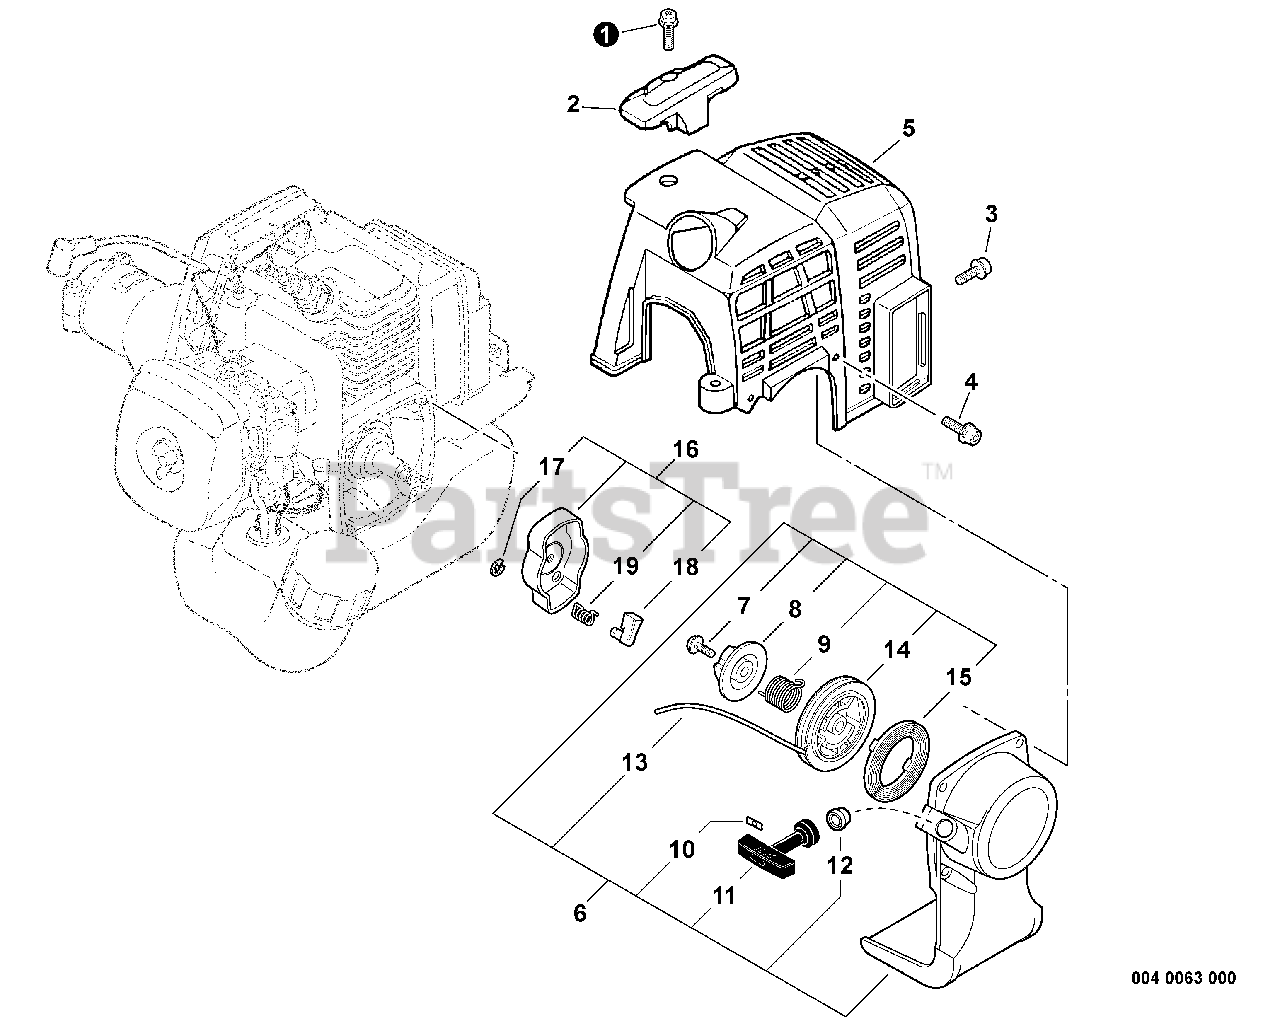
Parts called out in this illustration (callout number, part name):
1	SCREW 5×16
2	GUARD, TOP
3	BOLT 4×8
4	BOLT 4×16
5	COVER, ENGINE
6	STARTER, RECOIL
7	SCREW
8	PLATE, CAM (NLA SEE PB 15-06)
9	SPRING, TORSION
10	RETAINER, ROPE
11	GRIP, STARTER
12	GUIDE, ROPE
13	ROPE, STARTER 3×700
14	REEL, ROPE
15	SPRING, RECOIL
16	PAWL ASSY, STARTER
17	E-RING 4
18	PAWL, STARTER
19	SPRING, RETURN
